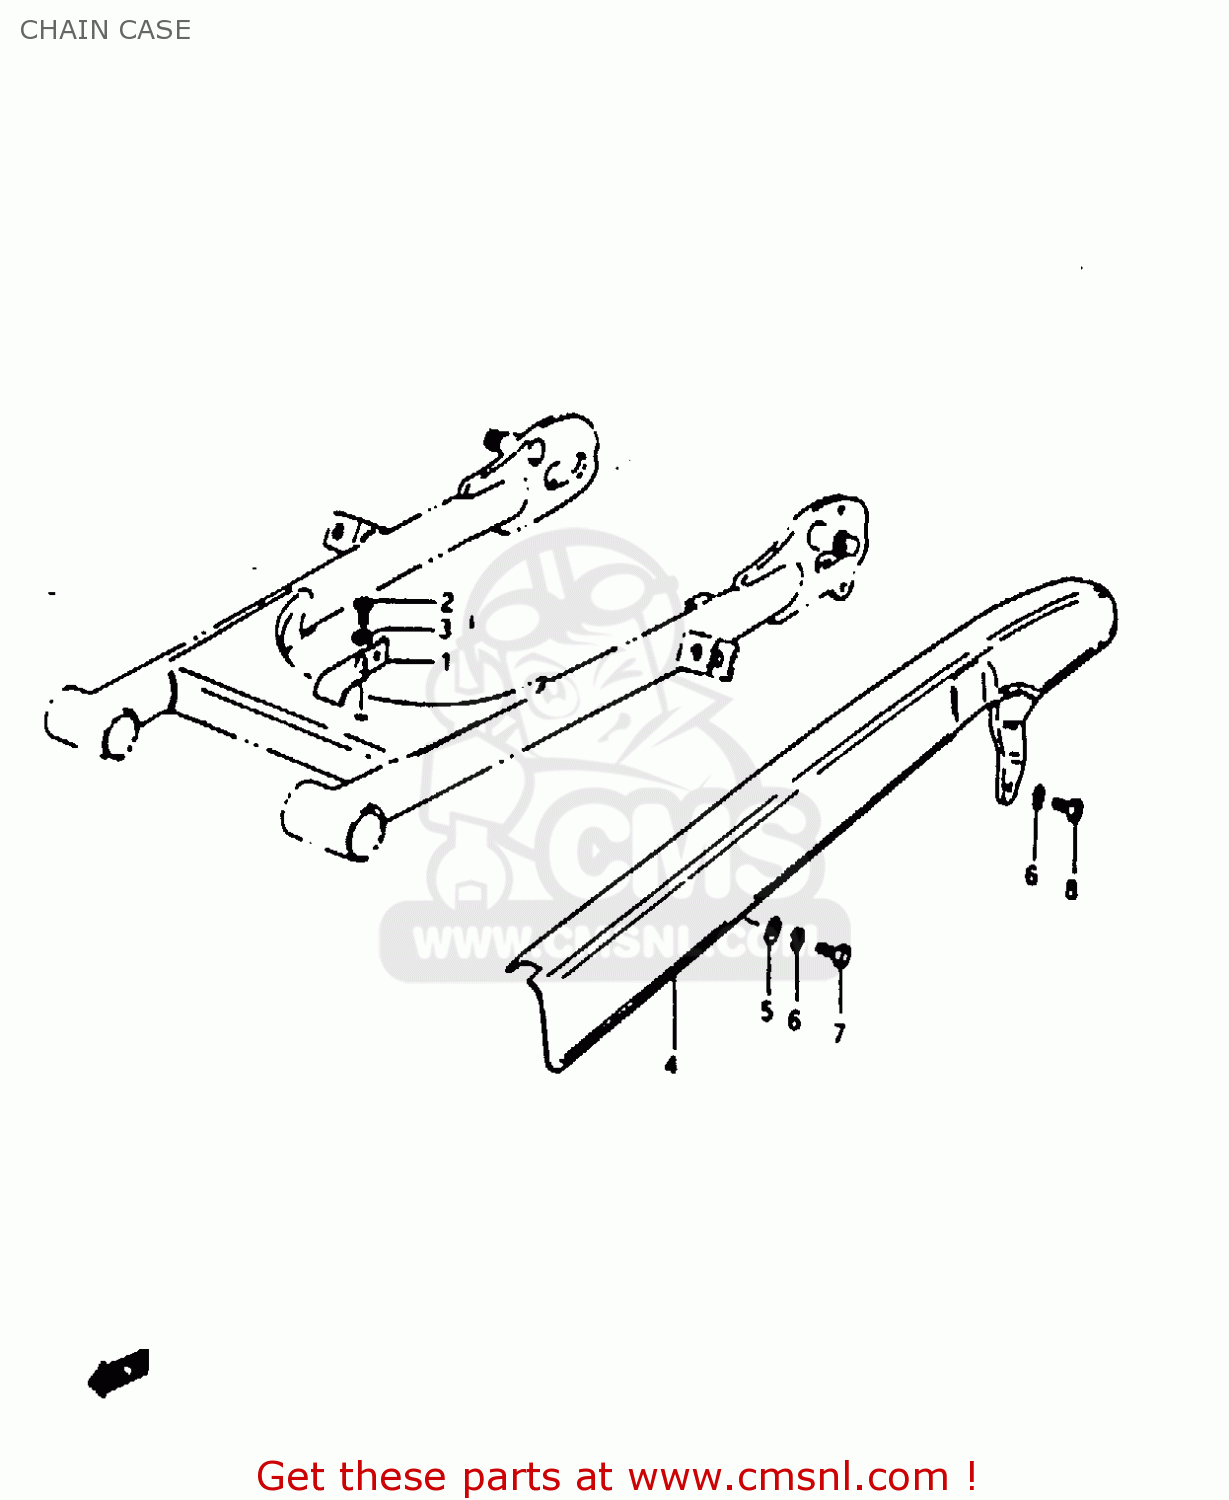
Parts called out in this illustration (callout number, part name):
1	BRACKET, CHAIN CASE FRONT
2	SCREW
3	WASHER,LOCK
4	CASE,CHAIN
5	WASHER
6	WASHER,LOCK
7	BOLT
8	BOLT
